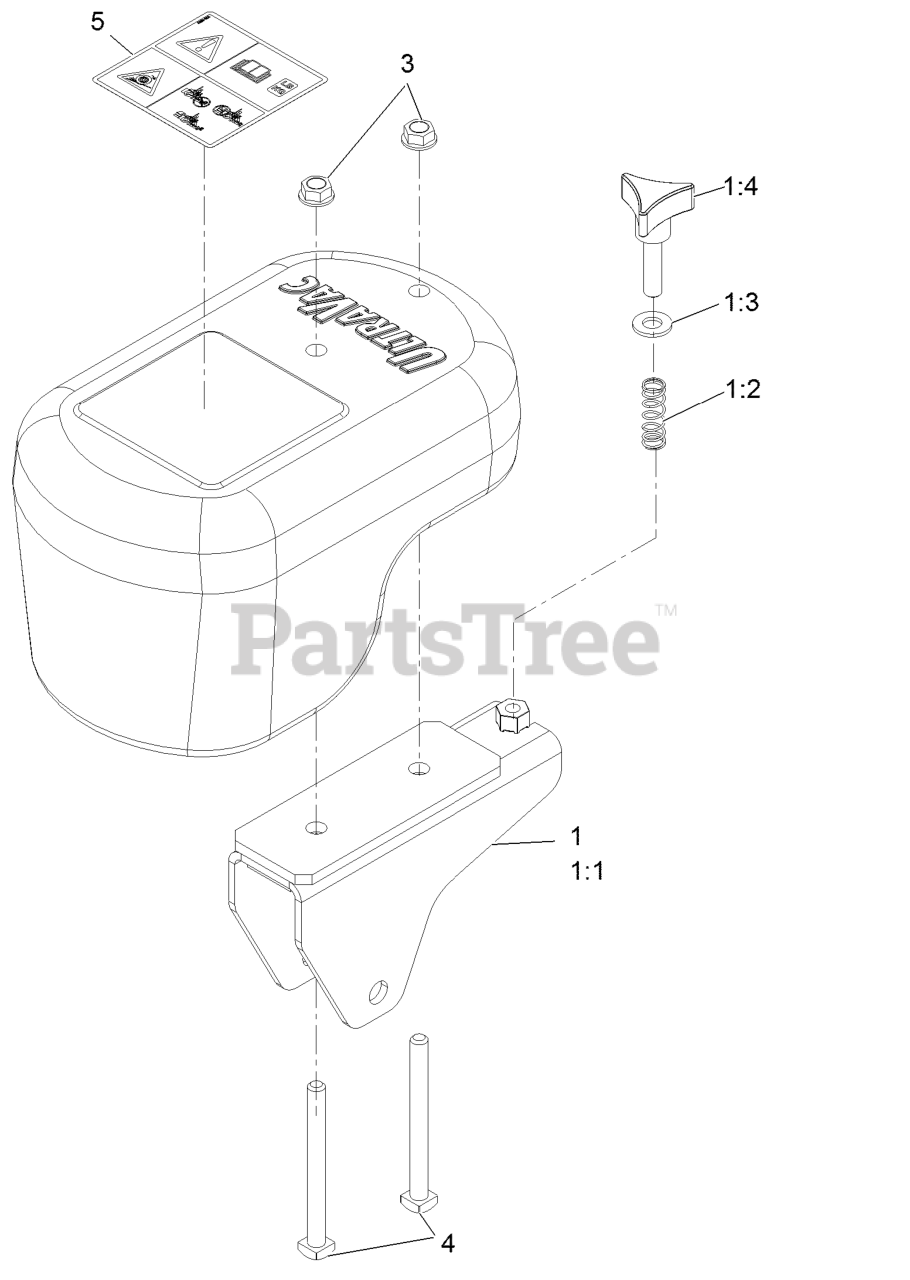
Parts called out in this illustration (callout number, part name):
1	ASM,Caster Weight Bracket
1:1	Wld,Caster Weight Bracket
1:3	Washer-3/8 SAE
3	Nut-Whizlock 3/8-16
4	Bolt-Square Hd 3/8-16 X 4
5	Decal-Warning, Traction
